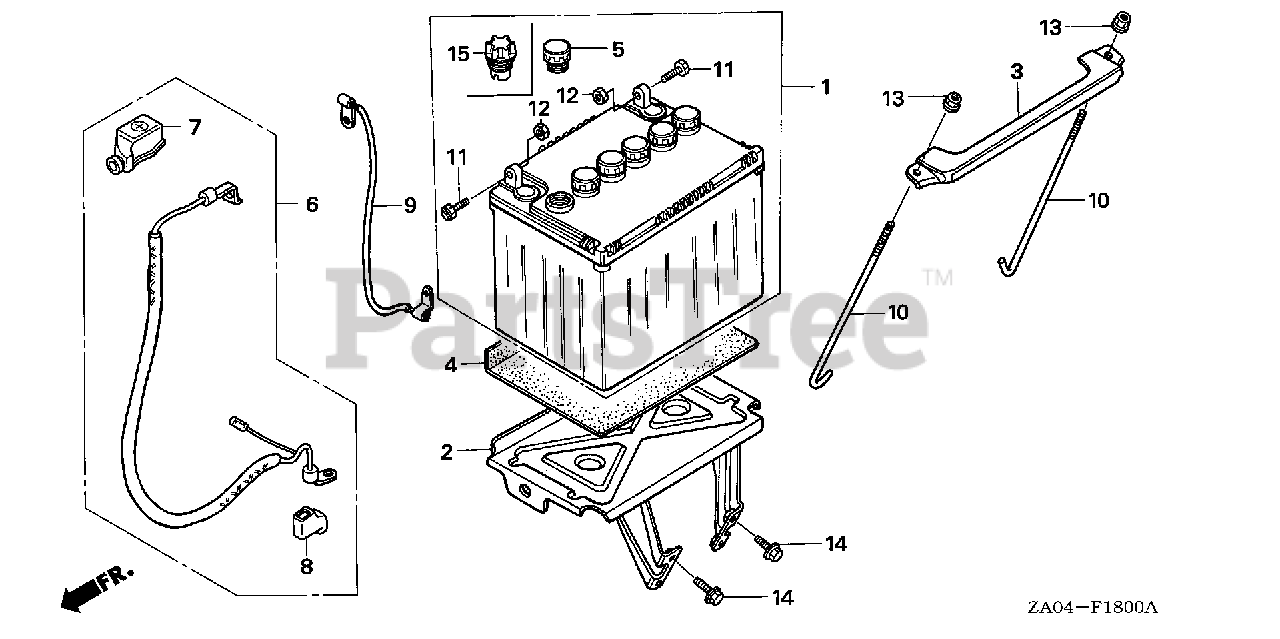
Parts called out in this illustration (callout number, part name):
1	BATTERY ASSY. (34A19L-MF) (YUASA)
2	HOLDER, BATTERY
3	PLATE, BATTERY SETTING
4	PLATE, BATTERY
5	PLUG, VENT (YUASA)
6	CABLE ASSY., STARTING
7	COVER, BATTERY
8	COVER B, MAGNETIC SWITCH (Honda Code 1059369). (NOT AVAILABLE)
9	CABLE, GROUND
10	BOLT, BATTERY SETTING
11	BOLT, BATTERY TERMINAL
12	NUT, BATTERY TERMINAL
13	NUT, FLANGE (6MM)
14	BOLT, FLANGE (6X12) Use up to Engine SN 1543277.
